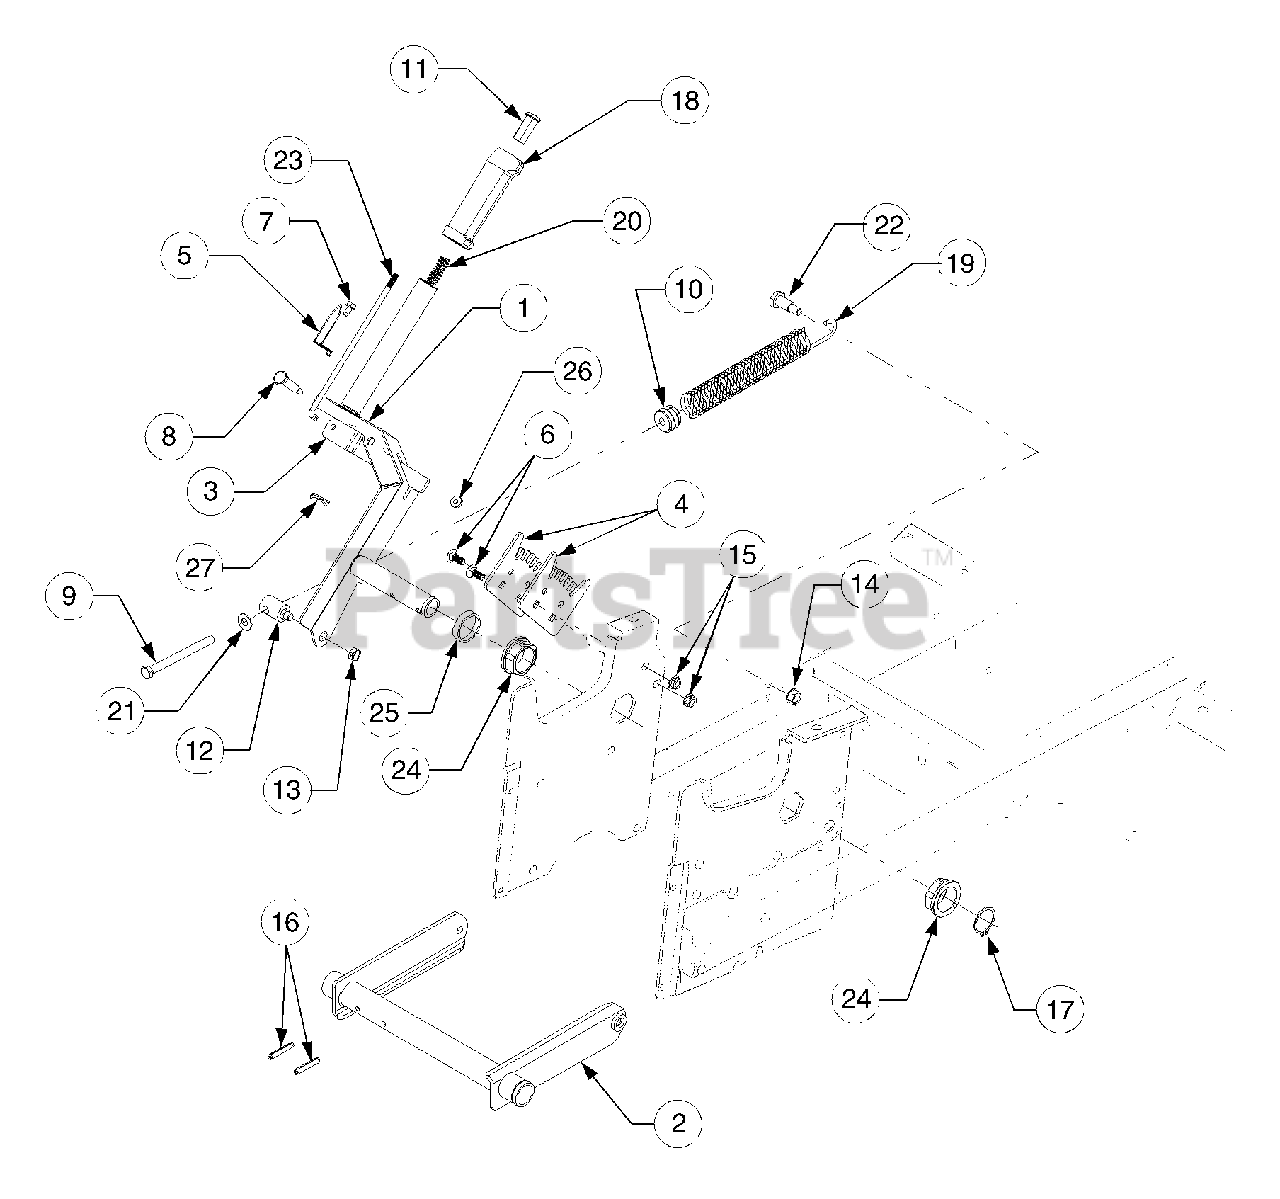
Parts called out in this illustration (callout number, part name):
1	Handle Assembly, Lift
2	Shaft Assembly, Lift
4	Bracket, Lift Index
5	Indicator, Lift Height
6	Bolt, Carriage, 5/16-18 x .75
7	Screw, Hex Wash Tapp, 1/4 x .5
8	Screw, Shoulder, .374 x 1.375
9	Screw, Hex Cap, 3/8-16 x 4.25 GR5
10	Insert, Spring
11	Button, Handle
12	Ferrule, Adjustment
13	Nut, Hex Center Lock, Jam, 3/8-24
14	Nut, Hex Flanged Lock, 3/8-16
15	Nut, Hex Flanged Top Lock, 5/16-18
16	Pin, Spiral Spring, 1/4 Dia x 1.5
17	Ring, Snap, 1.25 Dia Shaft
18	Grip, Lift Handle
19	Spring, Extension
20	Spring, Compression
21	Washer, Flat, .385 x .87 x .06
22	Bolt, Shoulder
23	Rod, Index
24	Bearing, Hex Flange, 1.25 ID
25	Spacer, 1.28 ID x 1.5 OD x .335 Lg
26	Nut, Hex Flange Lock, 1/4-20
27	Pin, Internal Cotter
